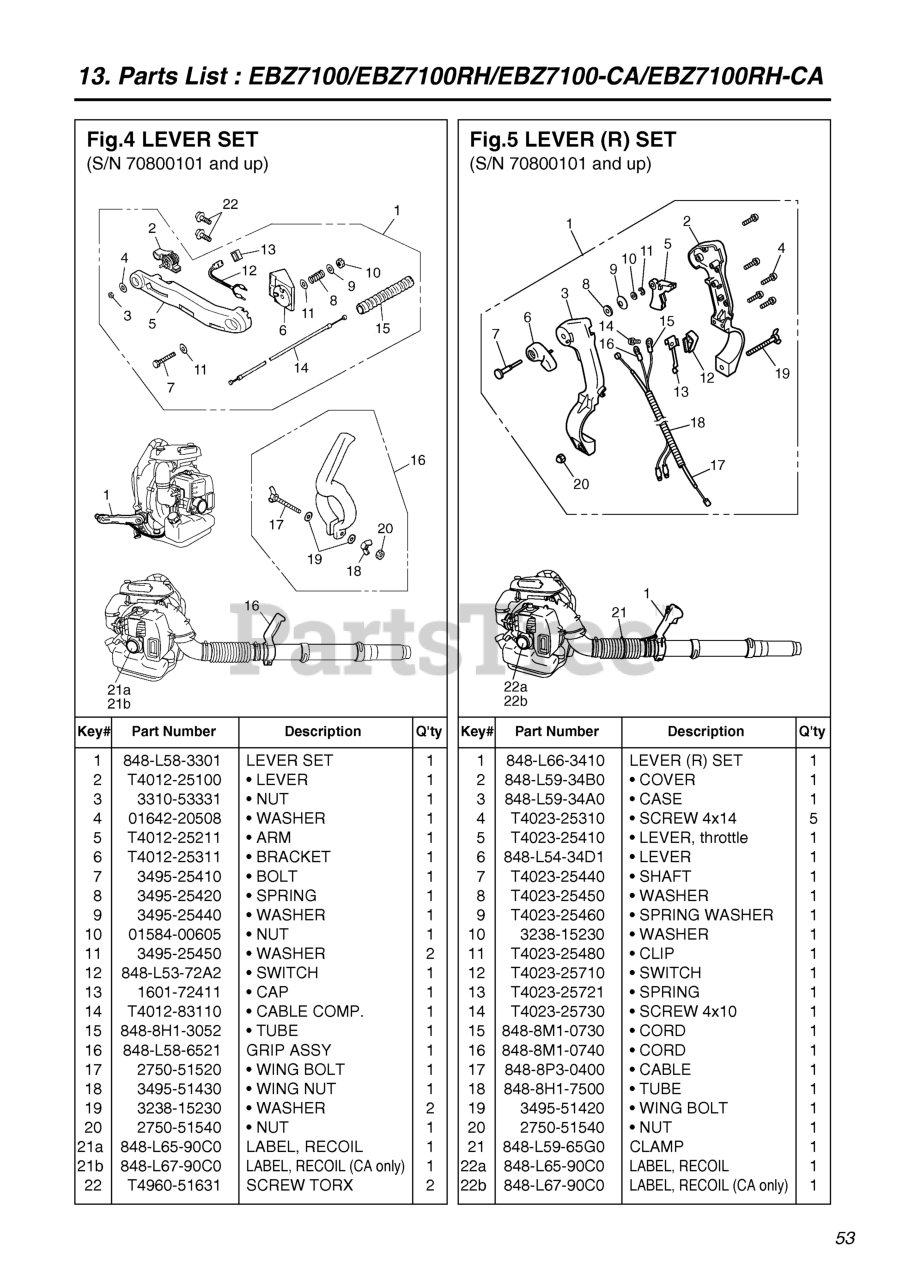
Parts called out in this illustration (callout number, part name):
1	LEVER SET
2	LEVER REPLACES T4012-22510
3	NUT (B)
4	WASHER, M5x.8(RPLS 01624-20508
5	ARM (RPLS T4012-25210)
6	BRACKET (RPLS -25310)
7	BOLT
8	SPRING
9	WASHER
10	FLANGE NUT, M6 x 5
11	WASHER, FLAT
12	SWITCH
13	CAP SWITCH
14	CABLE COMP
15	TUBE (REPLACES T4012-25610)
16	GRIP ASSY
17	WING BOLT
18	NUT, WING
19	WASHER
20	NUT
21A	LABEL, RECOIL
22	SCREW TORX
